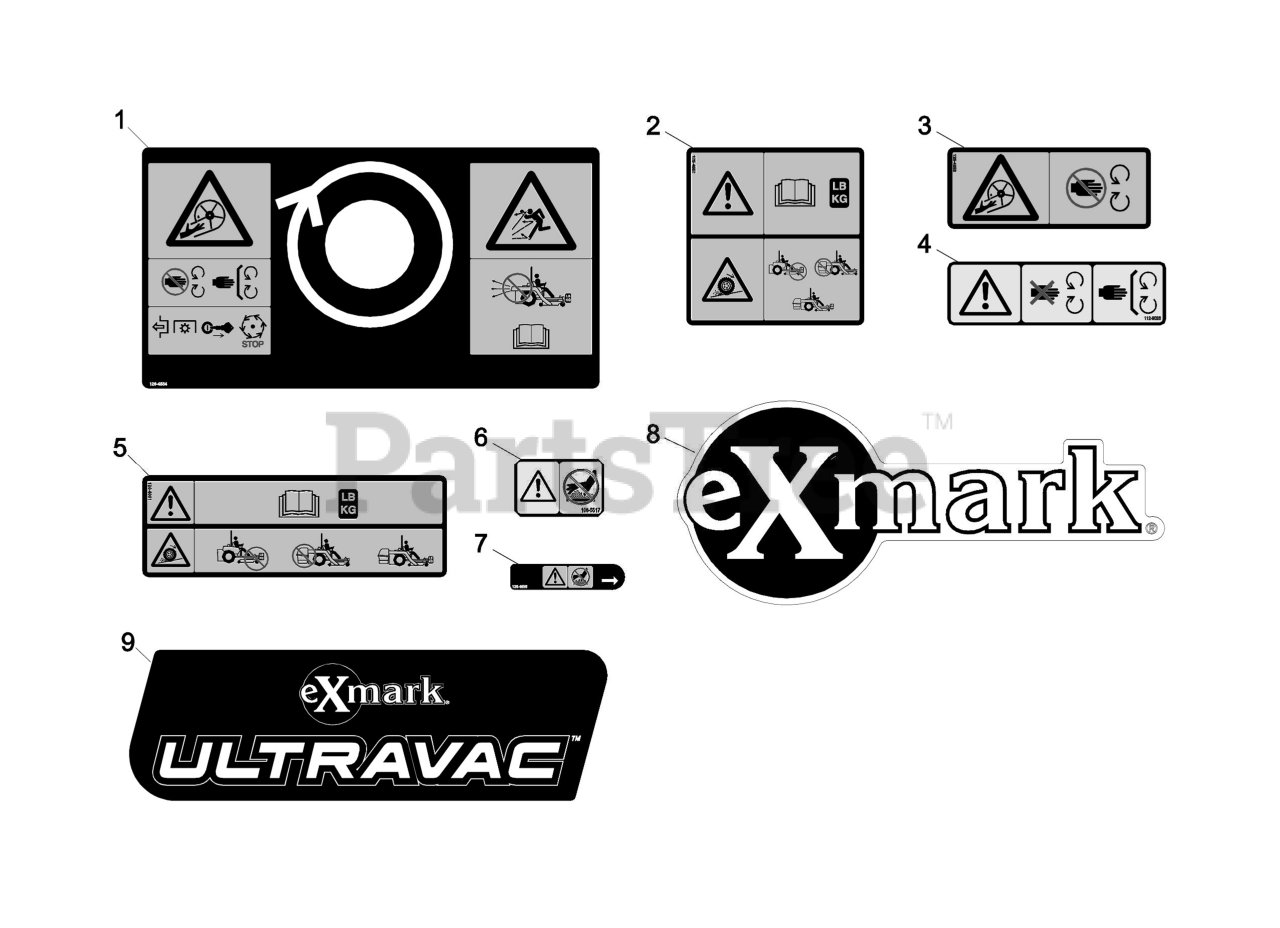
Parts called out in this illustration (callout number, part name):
1	Decal-Warning Blower
2	DECAL-WARNING, TRACTION
3	Decal-Blower-Impeller Hazard
4	DECAL-COVER, MISSING
5	DECAL-WARNING WEIGHT
6	DECAL-WARNING
7	DECAL-WARNING
8	DECAL-EXMARK LOGO
9	Decal, Ultra Vac
